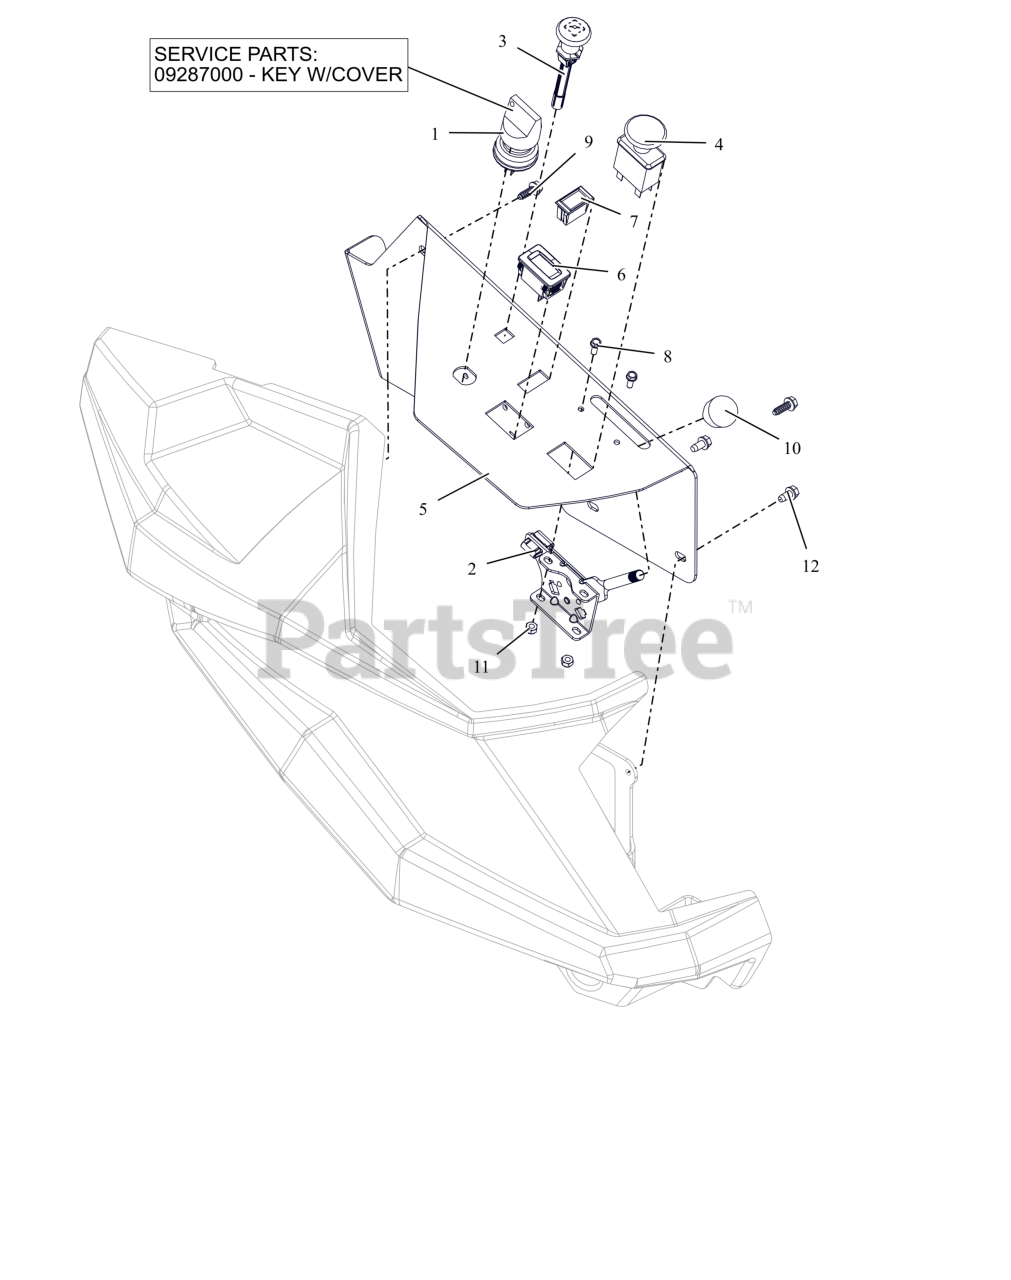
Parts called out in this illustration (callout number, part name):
1	SWITCH, IGNITION
1	KEY, W/ SHIELD
2	CABLE, PRO THROTTLE CONTROL
3	CABLE - CHOKE, SNAP-IN
4	SWITCH, CLUTCH
5	PANEL, HD CONTROL (RED)
6	HOUR METER
7	SWITCH,BLANK
8	BLT, HWH #10-24X.50 ZCC
9	SCR, PLASTITE-HWH 0.25 X 0.75 ZC120
10	KNOB-CONTROL-BLACK .38-16X.50
11	NUT-LK-NYL #10-24 G2 ZCC
12	SCR-TAP .25-20X.50 HWH ZCC
